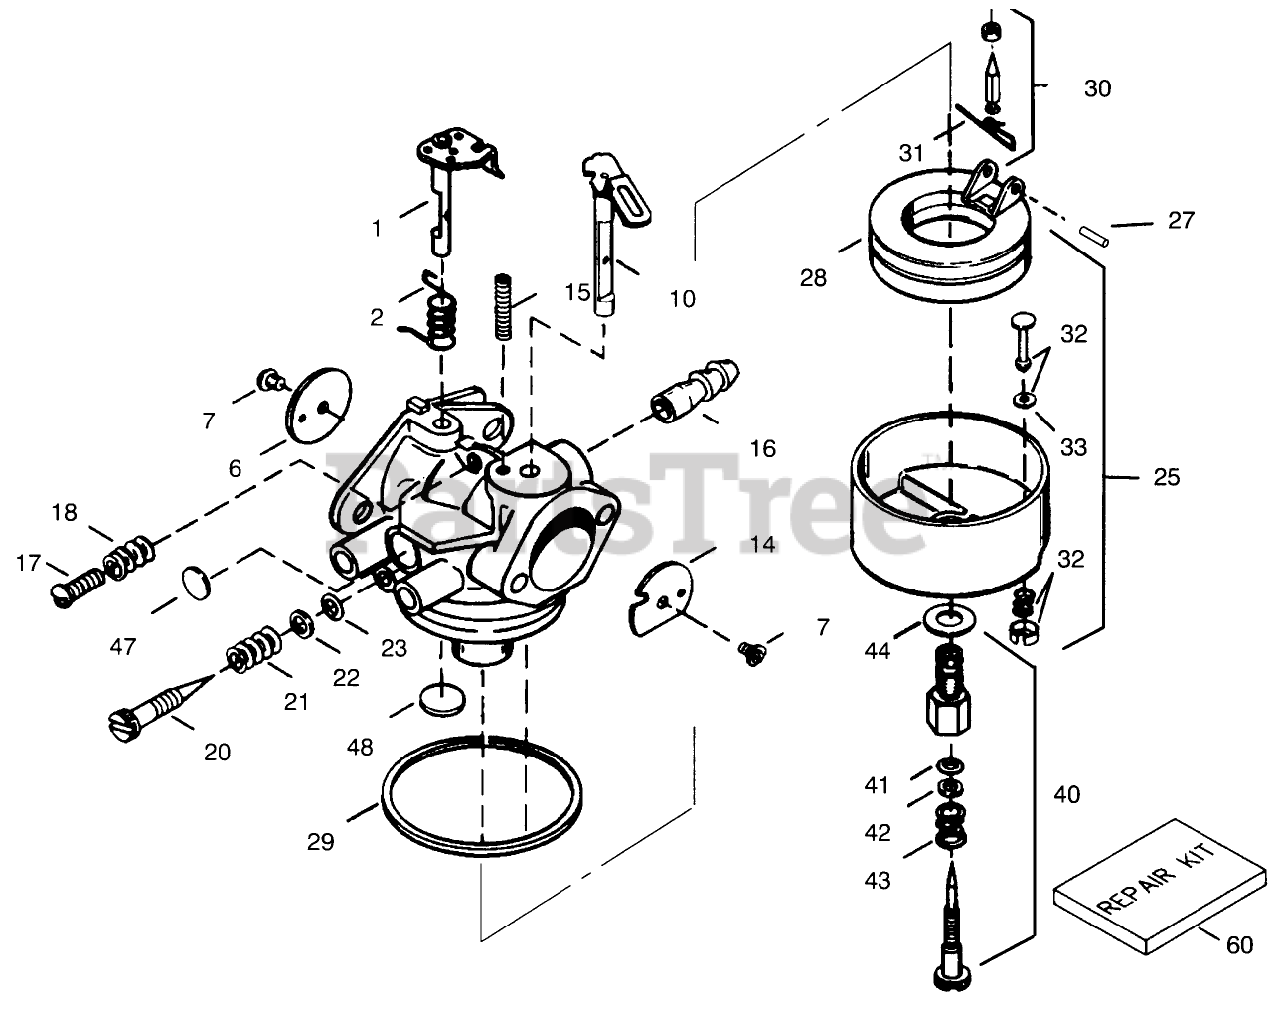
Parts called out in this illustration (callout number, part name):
1	Throttle Shaft and Lever ASM
2	Spring-Return, Throttle
6	Shutter-Throttle
7	Screw-Shutter
10	Choke Shaft and Lever ASM
14	Shutter-Choke
15	Spring-Positioning, Choke
16	Fitting-Fuel
17	Screw-Throttle Crack Screw / Idle Speed
18	Spring-Tension
20	Screw-Idle Mix
21	Spring-Tension
22	Washer
23	ORing
25	Float Bowl Asm. (Incl. Ref. # 32, 33)
27	Shaft-Float
28	Float
29	O Ring-Bowl, Float
30	Inlet Needle, Seat Clip Assy. (Incl. No. 13)
31	Clip-Spring
32	Bowl Drain ASM
33	Gasket-Plunger, Drain
40	Adjustment Screw Assy.,Main (Incl. Ref. #5A,21,23 30)
41	ORing
42	Washer
43	Spring
44	Washer-Bowl Nut
47	Plug-Welch, Idle Mixture Well
48	Plug-Welch, Atmospheric Vent
60	Kit-Repair
